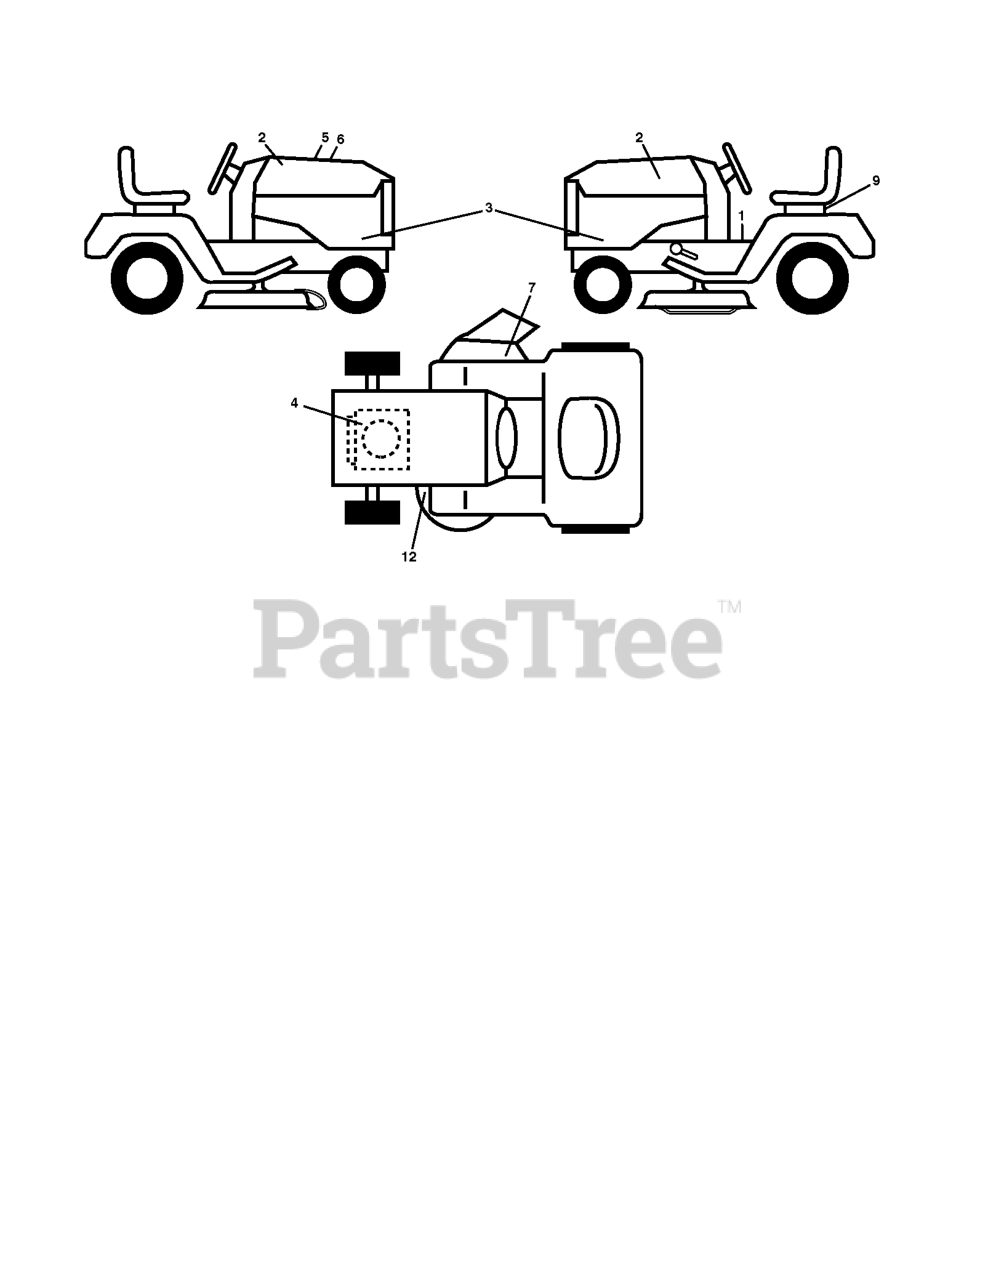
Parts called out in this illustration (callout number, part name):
1	DECAL.FENDER.WARNING.ENG
2	RP.DECAL.BADGE.170MM.TEXTLOGO
3	DECAL.SDPNL.YTH22V46.BS.HUSQ
4	Decal, Engine H.P.
5	DECAL.WARNING.CUST.RESP.E85.
6	Decal, Replacement
7	DECAL.WARN.KEEP.HAND.AWAY
9	DECAL BTRY SYMBOLS
12	DECAL V BELT SCHEMATIC
